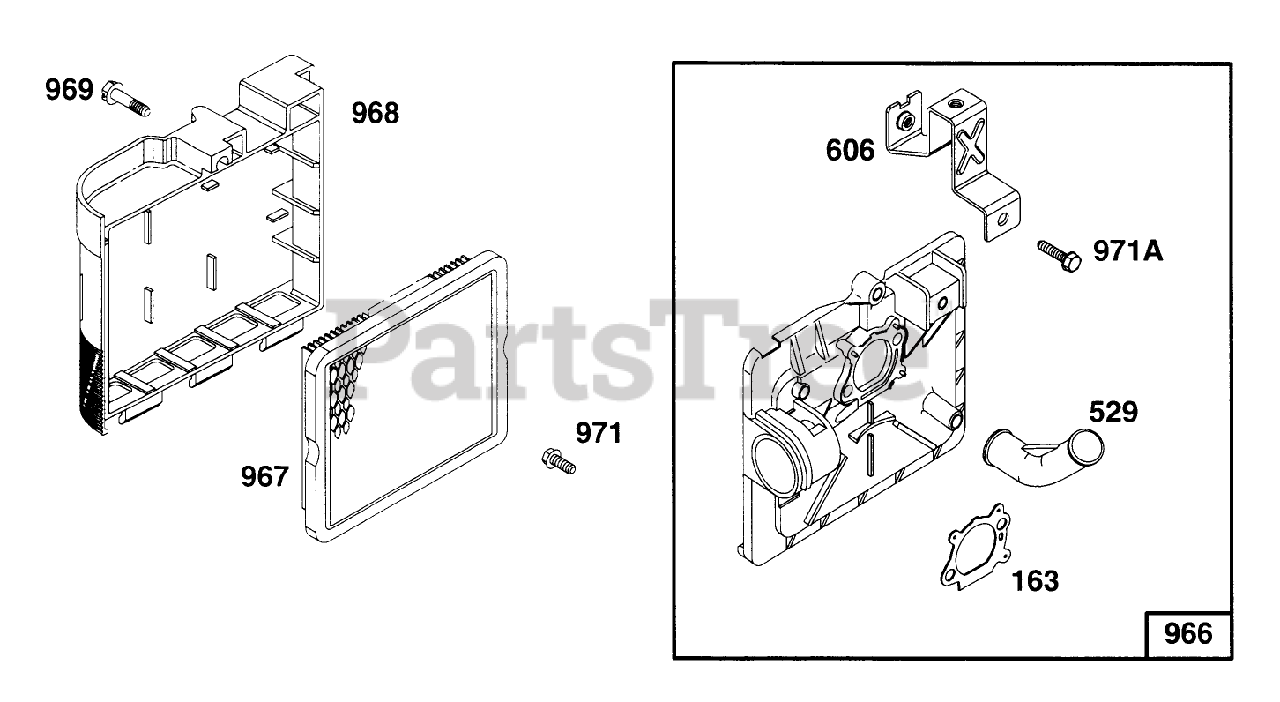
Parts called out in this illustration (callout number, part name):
163	Gasket-Cleaner, Air
529	Grommet
606	Strap-Bracket
966	Base-Primer, Air Cleaner
967	Filter-Air Cleaner, Cartridge
968	Air Cleaner Cover
969	Screw-Cover Mt.
971	Screw-Air Cleaner
971A	Screw-Hex.
